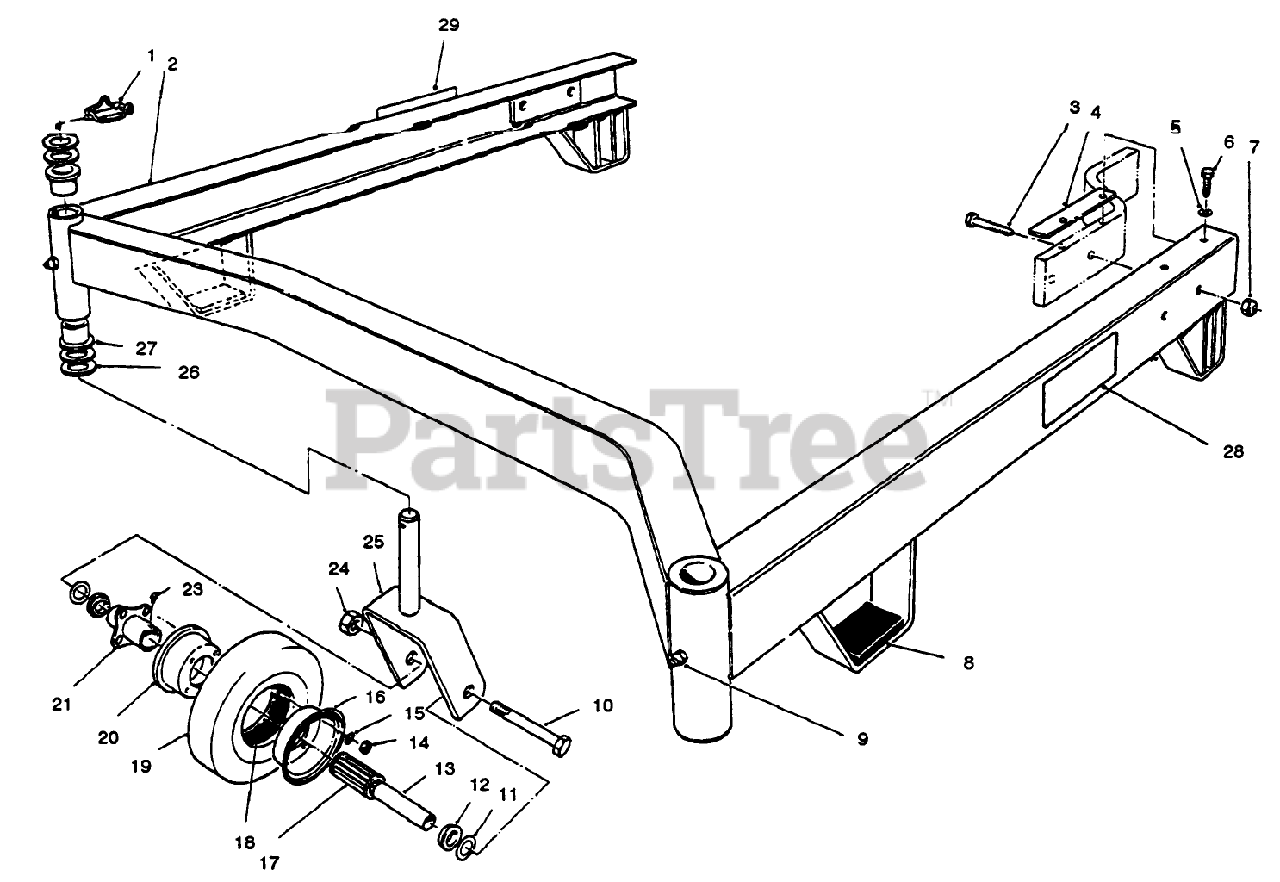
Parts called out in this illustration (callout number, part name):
1	PIN-LYNCH
3	SCREW-HH
4	SHIM-CARRIER
5	WASHER-FLAT
6	SCREW W/PATCH
7	NUT-LOCK, CONE
8	CUSHION-RUBBER
9	FITTING-GREASE
10	SCREW-HH
11	WASHER-FLAT
12	BEARING-OUTSIDE
13	SPANNER-TIRE
14	NUT-HEX
15	SCREW-HH
16	MALE WHEEL HALF
17	BEARING-ROLLER
18	TUBE-INNER (W/VALVE)
20	FEMALE WHEEL HALF
21	HUB-CENTER
23	FITTING-GREASE
24	NUT-HEX
26	WASHER-THRUST
28	DECAL-HOC, RH
29	DECAL-HOC, LH
